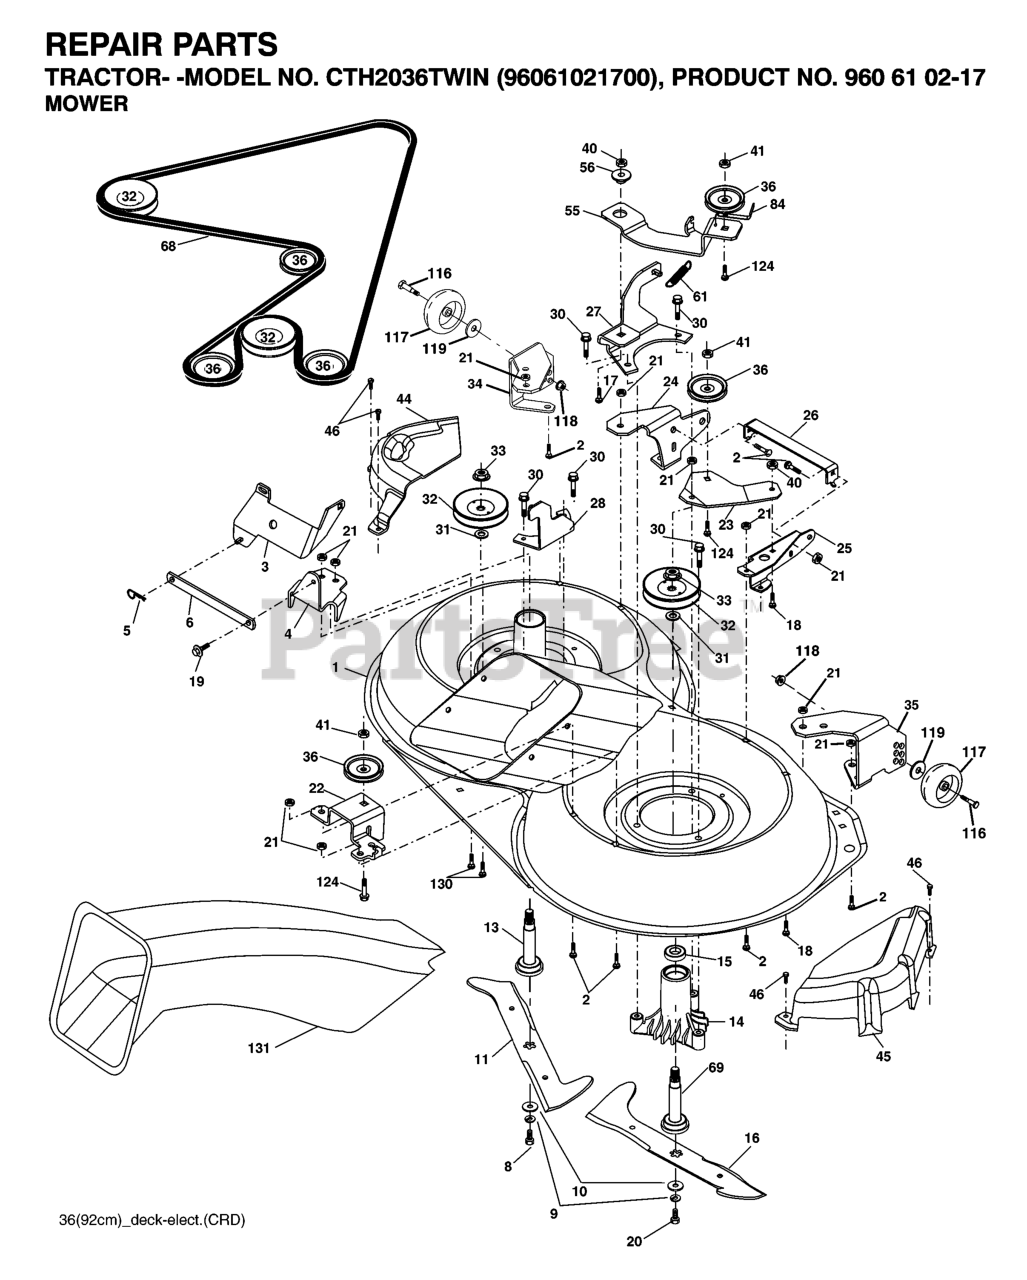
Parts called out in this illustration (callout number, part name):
2	RP BOLT 5/16-18 X3/4 ZN/YEL GR
5	RETAINER-SPRNG RB
6	BAR.SWAY.92.CRD
8	BOLT.3/8-24X1.25 GR8
9	LOCKWASHER
10	WASHER.BLADE
13	SHAFT ASM VENT
14	HOUSING.MANDREL.VENTED (MACHD)
17	BOLT.3/8-14X1.25
19	BOLT SHD 5/16-18
20	BOLT.3/8-24X1.25GR8. LHTHRD
21	LOCKNUT
26	SUPPORT
30	SCREW, WASHER HEAD
31	WASHER.SPACER.MANDREL
33	NUT.FLANGE.LOCK.TOP
36	PULLEY.IDLER.4.25
41	NUT LOCK FLG 3/8-16 UNC
45	COVER.MANDREL.RH.CRD
46	SCREW.1/4-20X5/8
55	ARM.IDLER.92 CRD.2006
56	SPACER.RETAINER.MOWER
61	SPRING
68	BELT.DRIVE.92CM.CRD.2006
69	SHAFT.ASM.W/LWR.BRG.RH.THREAD
84	KEEPER, BELT IDLER
116	BOLT.SHOULDER.3/8-16X3-5/8.
117	RP WHEEL. GUAGE RALLY
118	LOCKNUT
119	WASHER
124	BOLT.3/8-16X1.50
130	BOLT.CARR.SQNK.5/16-18UNC.X3/4
131	CHUTE BAGGER
